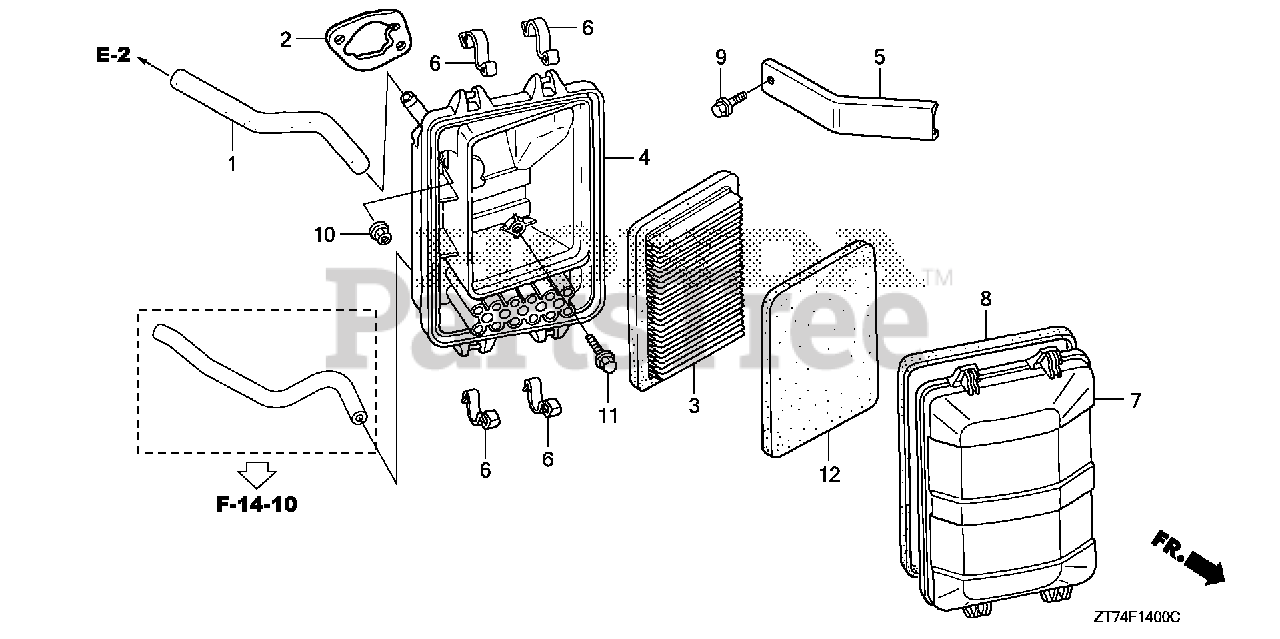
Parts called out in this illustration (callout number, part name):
1	TUBE, BREATHER
2	SPACER, CARBURETOR
3	ELEMENT, AIR CLEANER
4	HOUSING, AIR CLEANER
5	STAY, AIR CLEANER
6	SPRING, AIR CLEANER HOUSING LID
7	COVER, AIR CLEANER
8	SEAL, AIR CLEANER COVER
9	BOLT, FLANGE (6X16)
10	NUT, FLANGE (6MM)
11	BOLT, FLANGE (6X16) Use from Engine SN 2056820.
12	FILTER (OUTER)
